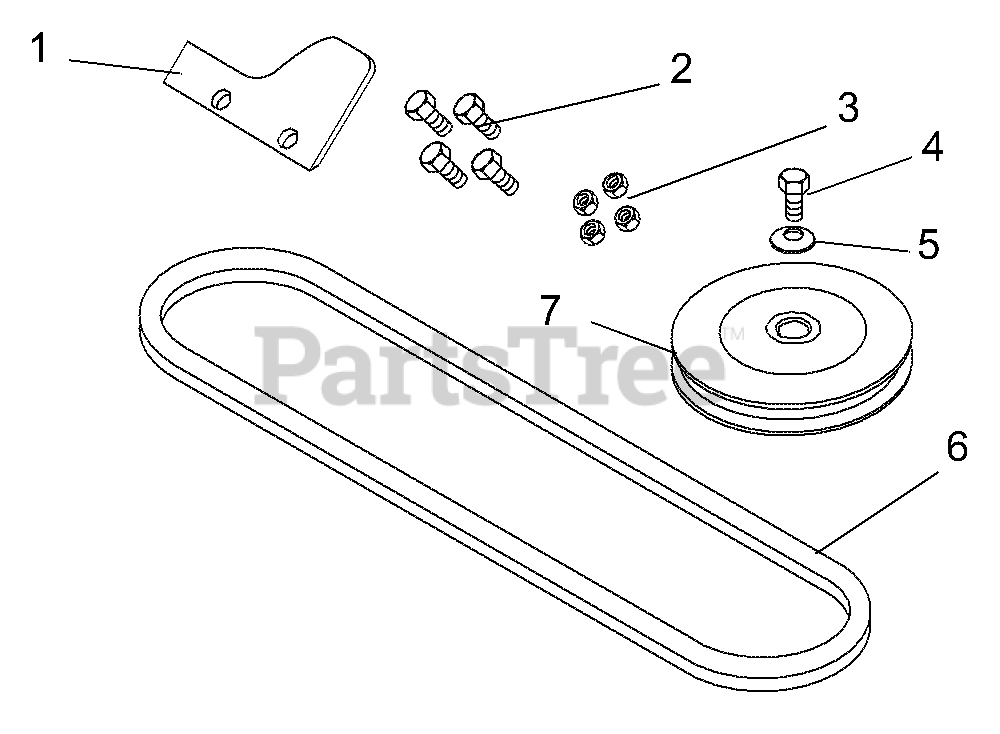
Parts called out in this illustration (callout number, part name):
2	5/16"-24 x 3/4" Hex Bolt
3	5/16"-24 Center Lock Nut
4	3/8"-16 x 1" Hex Bolt with Epoxy Patch
5	13/32" x 1-1/2" Flat Steel Washer
6	57-1/4" V-Belt (51512000)
6	62-1/2" V-Belt HA (51512100)
7	28" Deck Input Sheave (51512000)
7	32" Deck Input Sheave (51512100)
